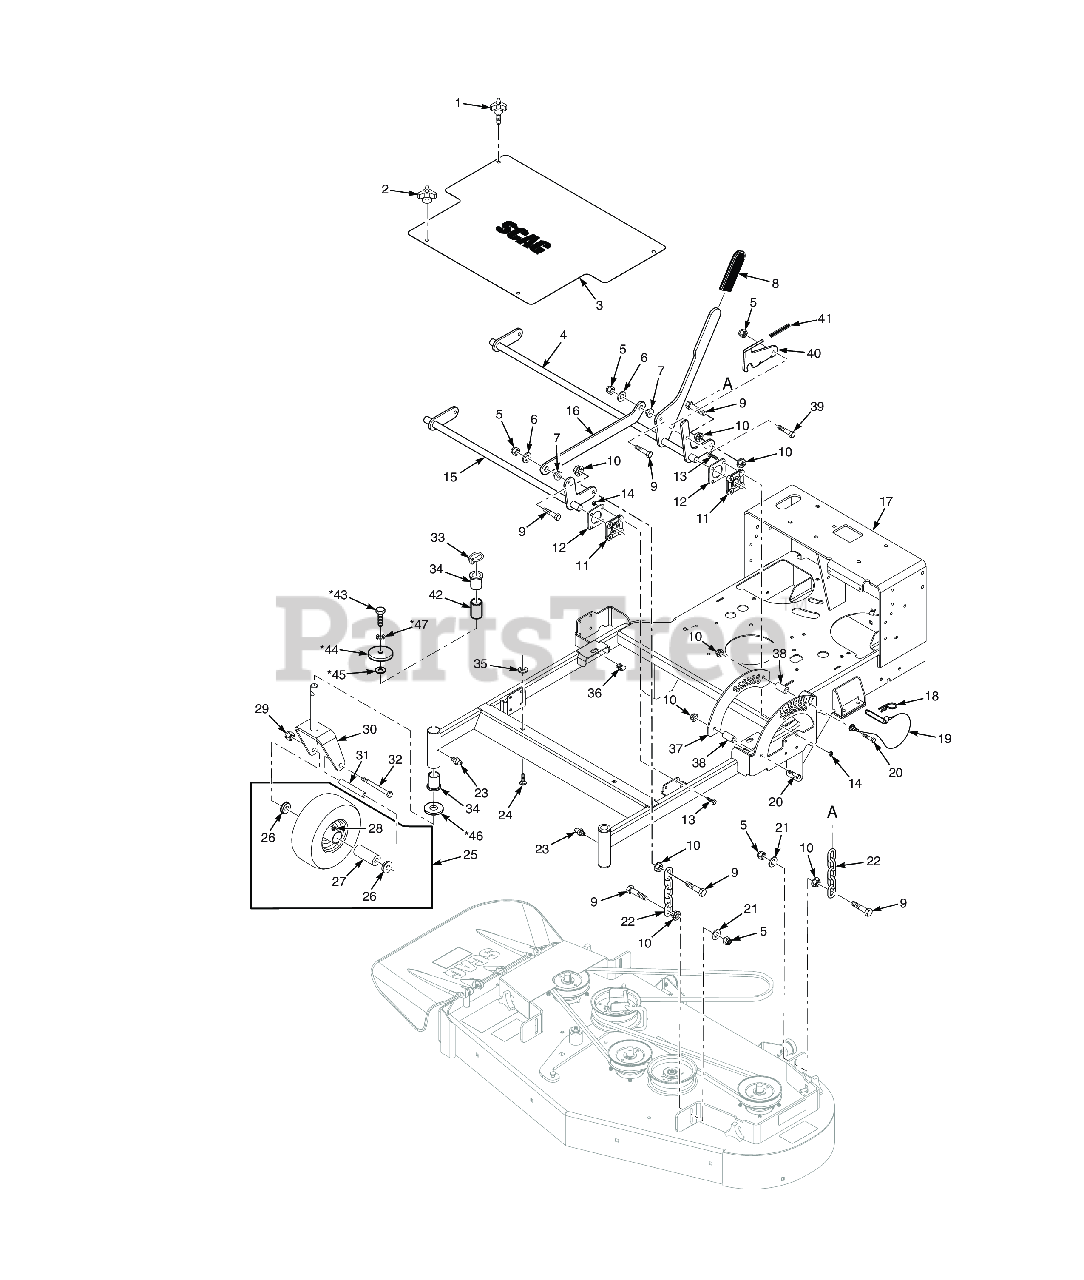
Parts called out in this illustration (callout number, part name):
1	Knob, w/stud 3/8-16 x 1-1/4"
2	Wing Nut, 3/8-16 (Small) Top side
3	Belt Cover w/Decals
3	Belt Cover w/Decals - SWZT61
4	Deck Bellcrank Assy.
4	Deck Bellcrank Assy. - SWZT61
5	HEX NUT, ELASTIC STOP LOCK, 3/8-16
6	Flatwasher, 3/8" Special (.391 x .938 x .105)
7	BUSHING, SPEED ADJUSTMENT LEVER
8	Grip, Deck Lift
9	Bolt, Hex Head, 3/8-16 x 1-1/2"
10	NUT, 3/8-16 SERRATED FLANGE HEX HEAD
11	Bearing, Deck Lift - 48V & 52V
12	Reinforcement, Bearing - 48V & 52V
13	Cpscrw, 5/16-18 x 1"Serrated Flange Hex Head
14	Nut, Center Lock, 5/16-18(32)
15	Deck Lift Weldment, Front
15	Deck Lift Weldment, Front - SWZT61
16	Link, Decklift
16	Link, Decklift -SWZT61
17	Frame w/Decals (SWZT 36 & 48)
17	Frame w/Decals (SWZT 52)
17	Frame w/Decals (SWZT 61)
18	Hair Pin Cotter, .177" x 3-1/4"
19	Lanyard, Deck Height Pin Assembly
20	Capscrew, Hex Head 3/8-16 x 2-1/2"
21	Flatwasher, 3/8" Special (.391 x .938 x .105)
22	Chain, Deck Lift
23	GREASE FITTING, STR. 1/4-28 SELF TAP.
24	Carriage Bolt, 3/8-16 x 1.0"
25	Flat Free Tire Assy.
25	Caster Wheel Assembly, 11 x 4.0-5
26	Retainer, Bearing, Caster Wheel
27	Roller Bearing, .625 x 3-1/4"
28	GREASE FITTING, 45 DEGREE 1/4-28
29	HEX LOCKNUT, ELASTIC STOP, 1/2-13
30	Caster Yoke Weldment
30	Caster Yoke - SWZT61
31	SLEEVE, CASTER WHEEL BEARING
31	Sleeve, Caster Wheel Bearing - SWZT61
32	Bolt, Hex Head 1/2-13 x 5-1/2" (Three Weights Installed)
33	Quick Pin, .438" Dia.
34	Bronze Bushing, 7/8 ID x 1.0 Flanged
35	Nut, Push-On - 3/8" Dia.
36	U-Nut, 3/8-16 (short)
37	Bracket, Deck Height
38	Spacer
39	Bolt, Hex Head, 3/8-16 x 1 Gr. 5
40	Lever Assembly, Deck Latch
41	Grip, Deck Transport Lock
42	Spacer, Caster Bearing
43	Bolt, Hex Head, 3/8-16 x 1 Gr. 5
44	Flatwasher, 3/8-.406 x 2.25" x .1875
45	Flatwasher, 7/16" (.500 x 1.25 x .083")
46	Spacer, Yoke
47	Lockwasher, 3/8" Spring, Kawasaki FX / FS
